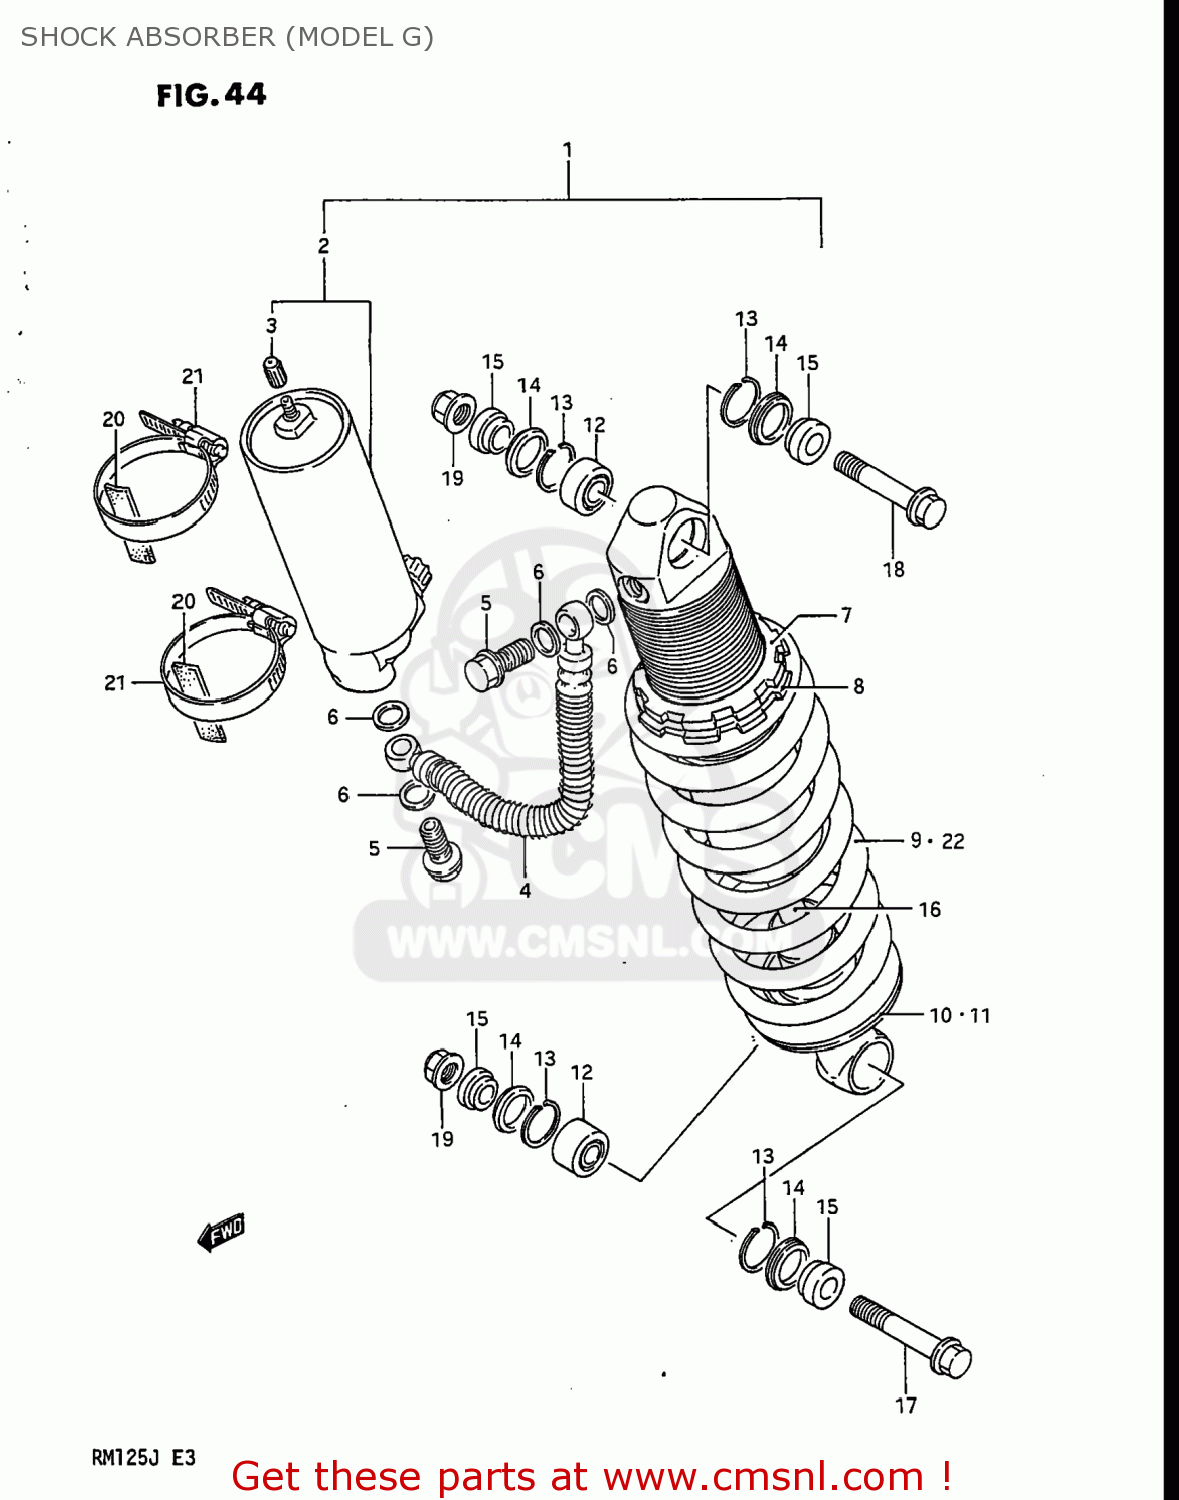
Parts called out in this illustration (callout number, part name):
1	ABSORBER ASSEMBLY,REAR SHOCK
2	TANK
3	CAP
4	HOSE
5	BOLT,REAR SHOCK ABSORBER
6	GASKET (NAS)
7	NUT
8	GUIDE,SPRING
9	SPRING
10	WASHER
11	GUIDE,SPRING
12	BEARING,REAR SHOCK ABSORBER
13	RING
14	SEAL,DUST RR SHOCK ABSORBER
15	COLLAR
16	ROD,PISTON
17	BOLT,REAR SHOCK ABSORBER
18	BOLT,UPPER
19	NUT
20	CUSHION,REAR SHOCK ABSORBER
21	CLAMP
22	SPRING
